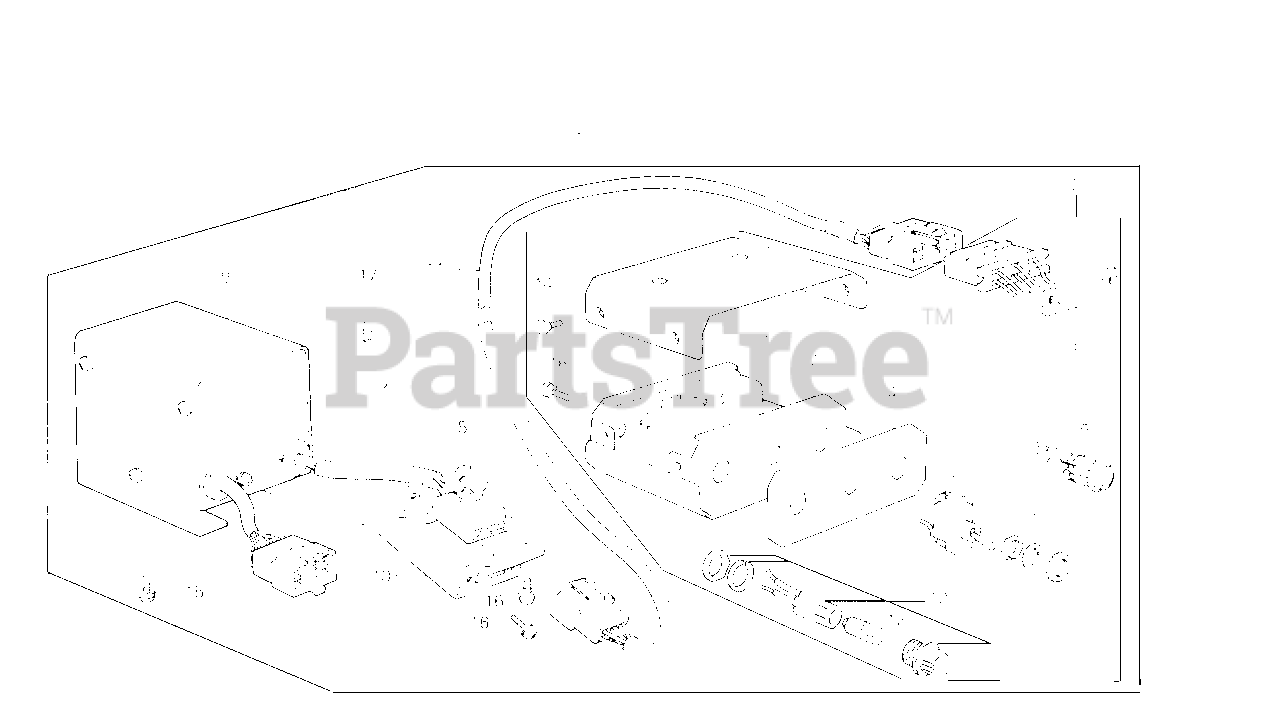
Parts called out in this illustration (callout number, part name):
1	CONTROL KIT, REMOTE (NOT AVAILABLE)
2	BOX ASSY., SWITCH
3	COVER (UPPER)
4	PANEL, FR.
5	PLATE, CONNECTOR SETTING
6	SWITCH, TOGGLE
7	CASE, SWITCH
8	SWITCH, PUSH
9	BOX ASSY., RELAY (NOT AVAILABLE)
10	HOLDER, CONNECTOR
11	CABLE, REMOTE CONTROL
12	BULB (24V2W)
13	SOCKET ASSY., PILOT LAMP
14	SCREW, FLAT (4X8)
15	SCREW-WASHER (5X12)
16	SCREW-WASHER (4X12)
17	BAND B1, CABLE
